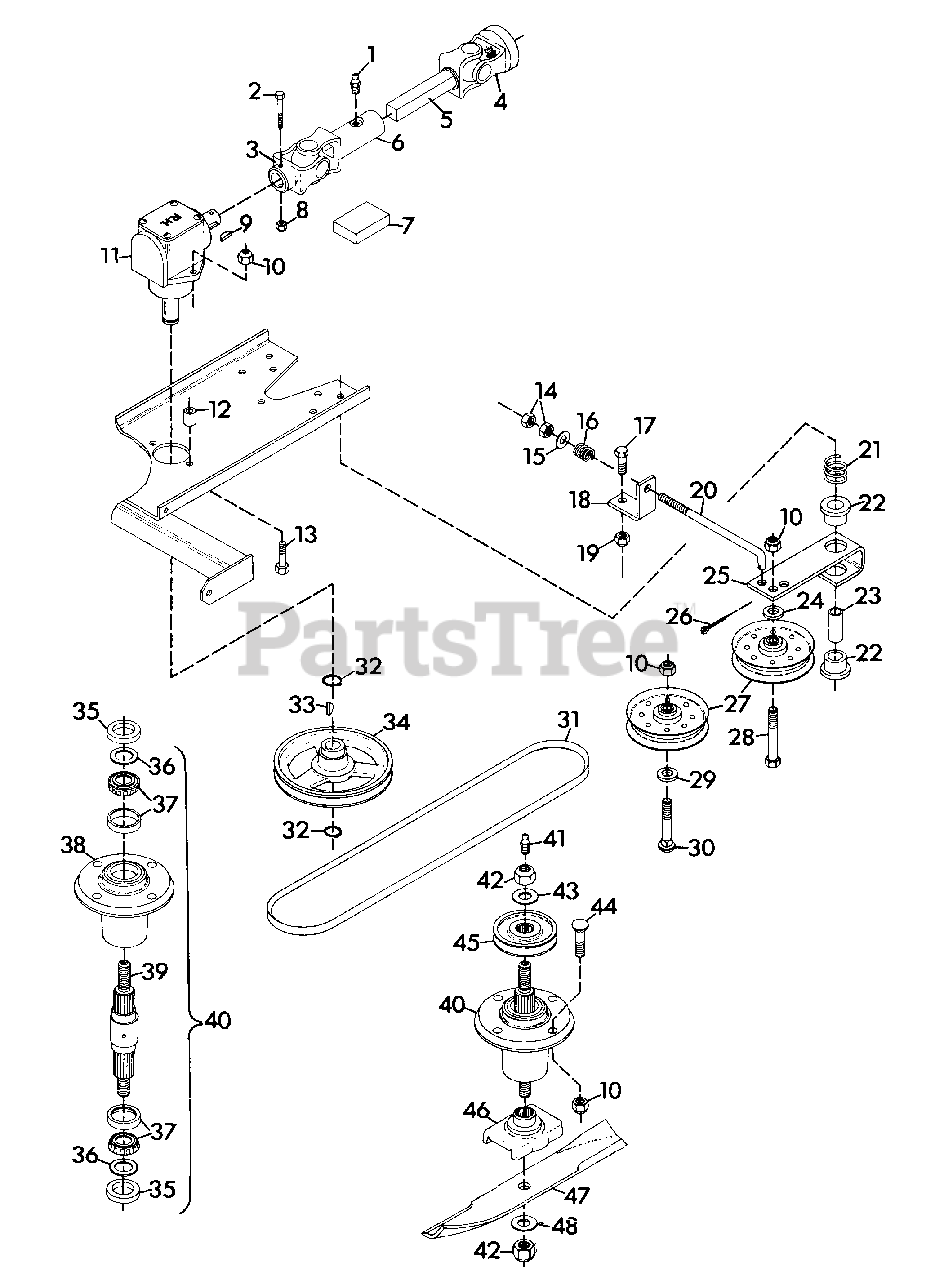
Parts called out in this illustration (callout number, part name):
1	Fitting, Lube 1/4-28
2	Bolt, Hex 1/4-20x2.00
3	Yoke
4	Yoke
5	Shaft, Prop. Sq. Bar
6	Assembly, U-Joint
7	Kit, Repair U-Joint(Rockwell)
8	Nut, Lock 1/4-20
9	Key, Woodruff .187x.75 Hard #9
10	Nut, Lock 3/8-16
11	Gearbox, Pro Master-50
12	Spacer, .375x.100x1.00
13	Bolt, Hex 3/8-16x2.25
14	Nut, Hex 3/8-24
15	Washer, Flat .406x.812x.065
16	Spring, Compression
17	Bolt, Hex 1/2-13x1.375
18	Support, Spring
19	Nut, Lock 1/2-13
20	Rod, Idler
21	Spring, Compression
22	Bushing, Nylon .760x1.00x.600
23	Spacer
24	Spacer, Idler .406x.750x.188
25	Arm, Idler Pivot
26	Pin, Cotter .09x1.00
27	Sheave, Idler
28	Bolt, Hex 3/8-16x2.00
29	Washer, Flat .438x1.000x.083
30	Bolt, 3/8-16x1.75 Rd Hd Sq Nk
31	Belt, V .500x.312x126.3
32	Ring, Retaining .875 Shaft
33	Key, Woodruff .250x.875 Hard #A
34	Sheave, Drive
35	Seal, Steel
36	Washer, Flat .975x1.970x.030
37	Assembly, Bearing Cup and Cone
38	Housing, Bearing
39	Shaft, Spindle
40	Assembly, Spindle
41	Fitting, Lube 1/8(Left and Right Spindle)
41	Fitting, Lube .125 Ext.(Center Spindle)
42	Nut, Lock 5/8-11
43	Washer, Flat .687x1.312x.122
44	Bolt, 3/8-16x1.25 Rd Hd Sq Nk
45	Sheave, Spindle
46	Weldment, Blade Cradle
47	Blade
48	Washer, Flat .656x1.312x.095
38069	Assembly, Pro Master-50 Drive
